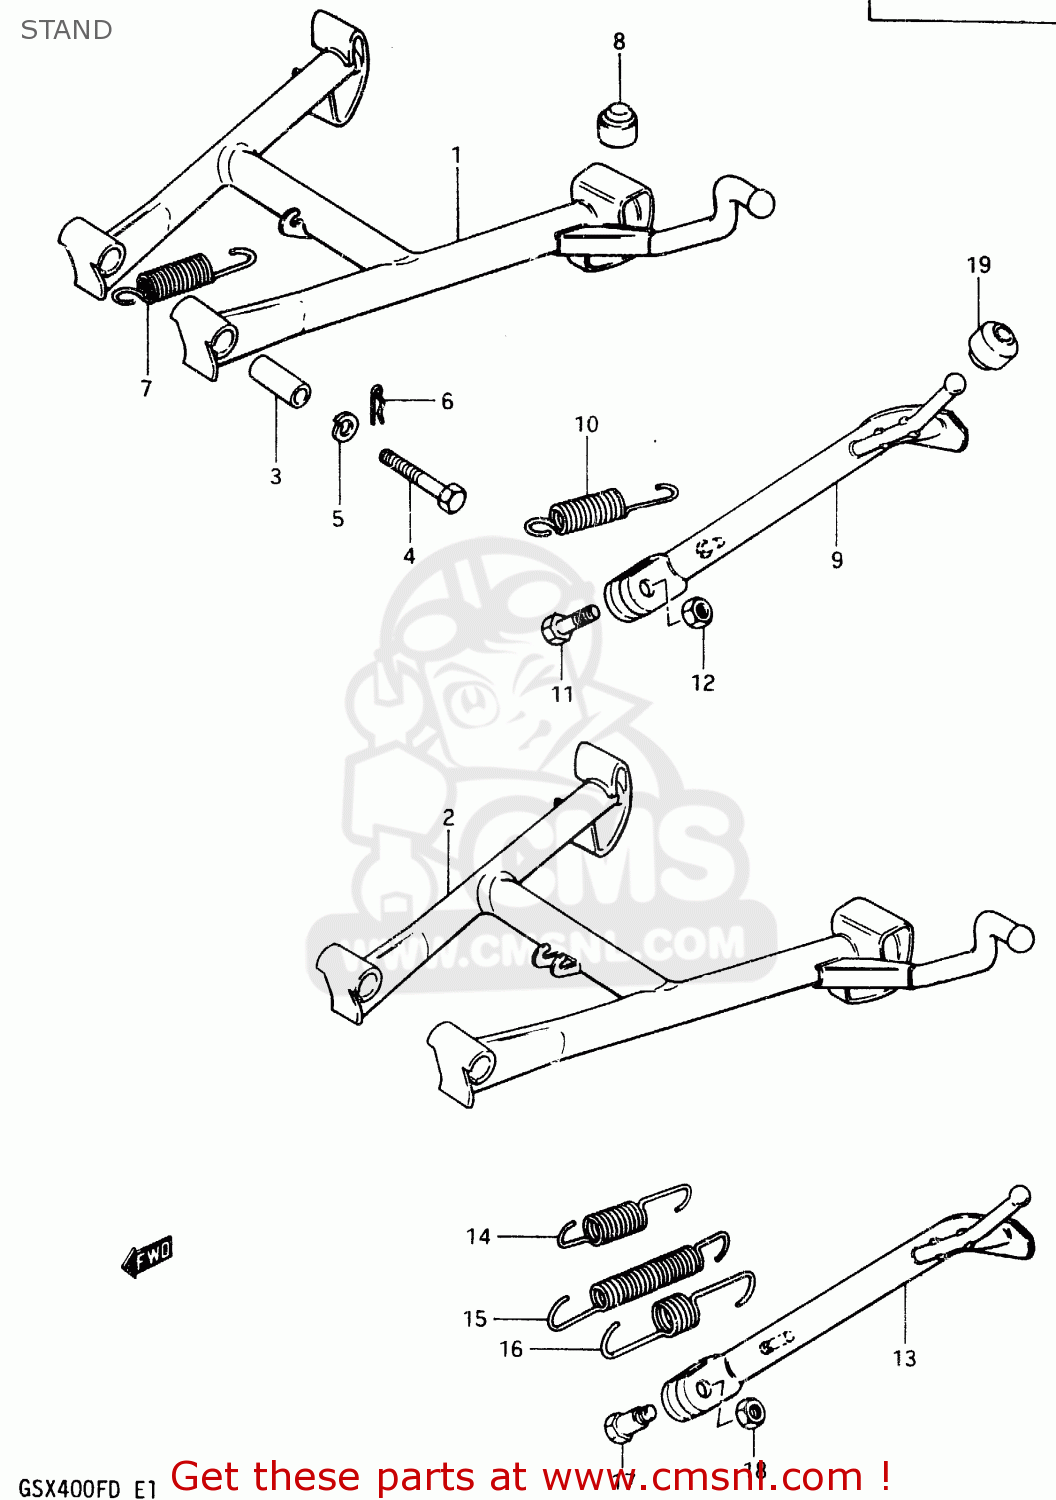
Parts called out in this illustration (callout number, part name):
1	STAND, CENTER
2	STAND, CENTER
3	SPACER(10X16X38.8)
4	BOLT
5	LOCK WASHER
6	CLIP
7	SPRING
8	CUSHION
9	STAND, PROP
10	SPRING
11	BOLT(10X30)
12	NUT
13	STAND, PROP
14	SPRING
15	SPRING
16	SPRING, OUTER
17	BOLT L:30
18	NUT
19	CUSHION
